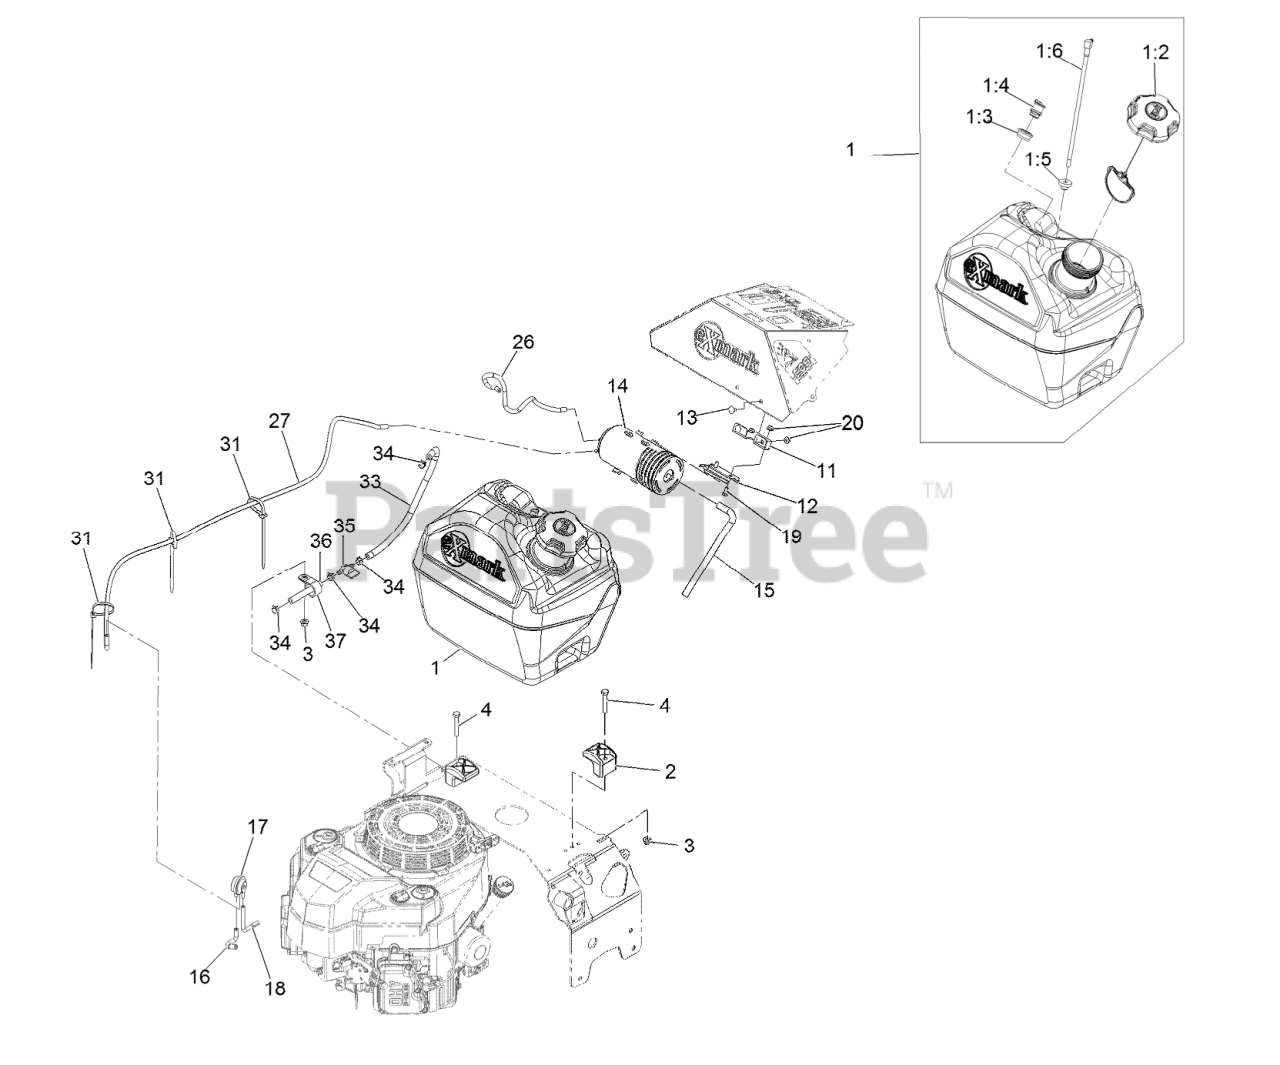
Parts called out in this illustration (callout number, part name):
1:2	CAP-FUEL, RATCHETING (3.5)
1:3	GROMMET
1:4	VALVE-VENT, FUEL
1:5	BUSHING
3	NUT-HF, NI
4	SCREW-HH
11	BRACKET-CANISTER, CARBON
12	BRACKET-CANISTER, CARBON
13	SCREW-CARR
14	CANISTER-CARBON, 800CC
15	HOSE-VENT, CANISTER
16	HOSE-VENT, FORMED
17	VALVE-CONTROL, VACUUM
18	HOSE-VENT, FORMED
19	SCREW-HH
26	HOSE-EMISSIONS
27	HOSE-VENT, FORMED
31	TIE-PLASTIC
33	HOSE-FUEL
34	CLAMP-HOSE
35	VALVE-FUEL
36	HOSE-FUEL
37	CLIP-LOOM
